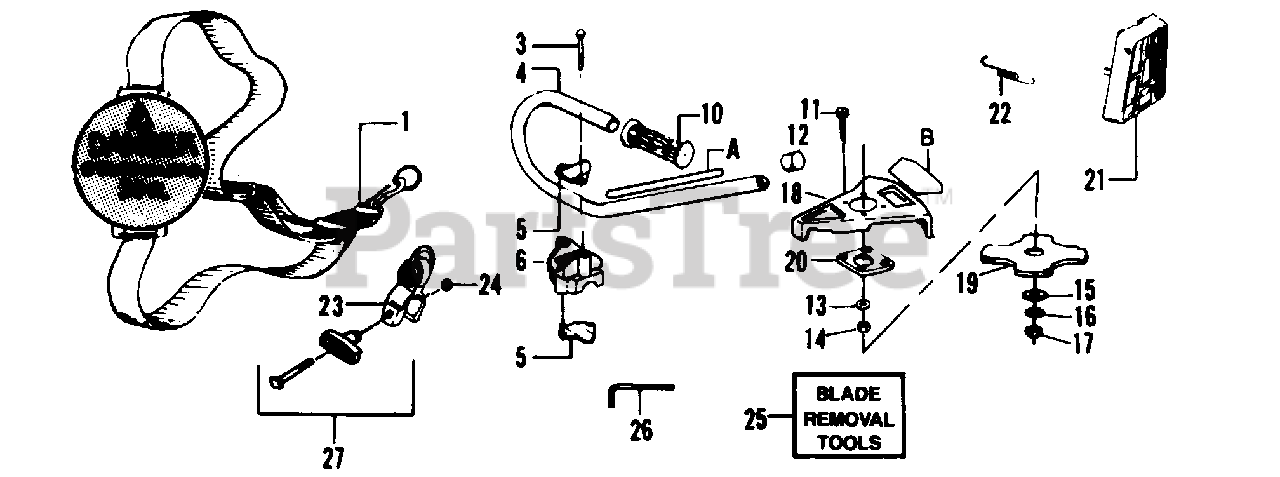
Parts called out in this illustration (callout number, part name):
1	Shoulder Strap (Inc. Key Ring)
3	Bolt-1/4-20x2" Hex
4	Barrier Handlebar
5	Handlebar Bracket
6	Handlebar Clamp
10	Grip-Handlebar
11	Screw-#1/4-20x1" Hex
12	End Cap Handlebar
13	Washer-1/4" Flat
14	Nut-Deflector to Brg. Hsh. (#1/4-20)
15	Washer-Flat
16	Washer-Bevel
17	Flange Nut
18	Shield-Aluminum
19	Blade-4 Tooth Weed
20	Shield Retention Plate
21	Muffler Guard
22	Muffler Guard Spring
23	Clamp Harness Ass'y
25	Blade Removal Tools
26	Hex Wrench
27	"T" Handle Kit
A	Decal-Handlebar Warning
B	Decal-Blade Rotation Warning
